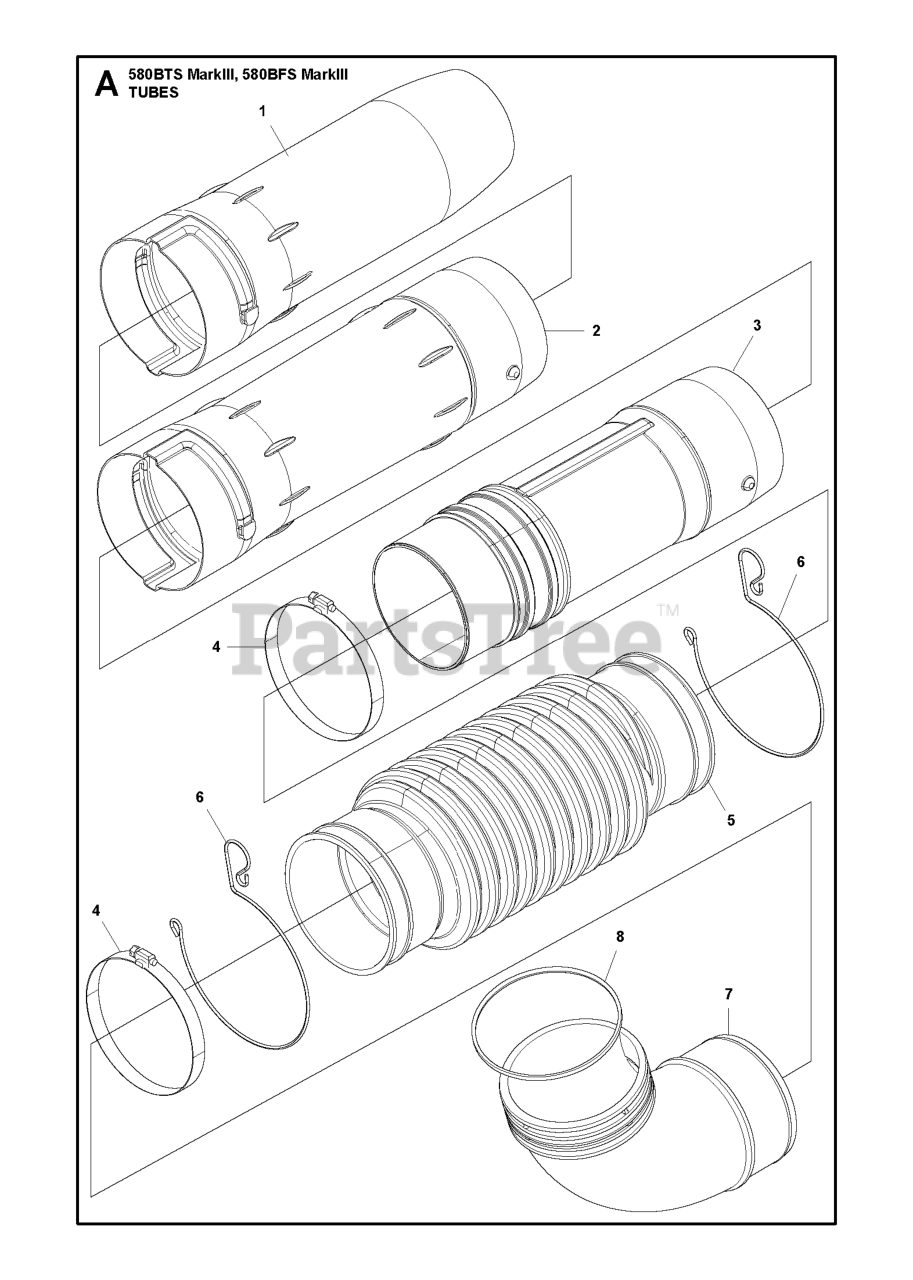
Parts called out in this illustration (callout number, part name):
1	PIPE END HUSQVARNA GREY
2	PIPE STRAIGHT HUSQVARNA GREY
3	PIPE,SWIVEL HUSQVARNA GREY
4	CLAMP FLEXIBLE
5	HOSE,FLEXIBLE BLACK
6	CLAMP, TH CABLE
7	ELBOW GRAY
